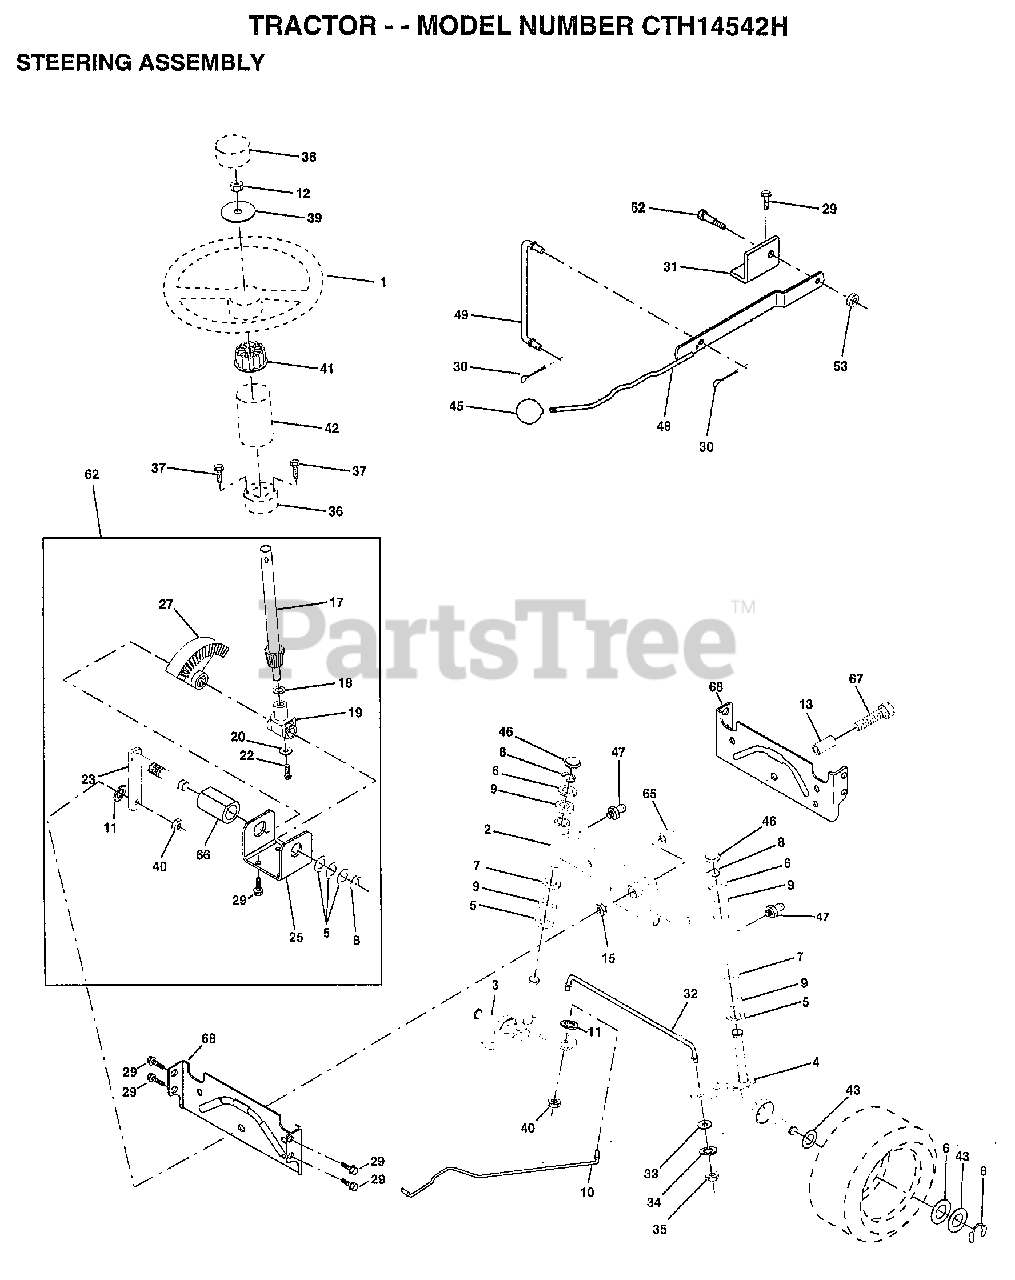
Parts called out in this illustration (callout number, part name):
1	WHEEL STR AYP BLK
2	AXLE ASM
3	SPINDLE.ASM.LH
4	"SPINDLE ASM,RH"
5	WASHER .T
6	WASHER
7	WASHER
8	RING
9	COL. SRTG. BEAR.
10	DRAGLINK-STAMPED
11	LOCKWASHER
13	BEARING AXLE
15	"NUT-LOC,FLANGE LT"
17	SHAFT ASM STEERNG
18	THRUST WASHER
19	SUPPORT.SHAFT
22	SCREW HEX SOC1/4-
25	BRKT-STEERING
27	GEAR SECTOR
29	SCREW
30	COTTER PIN
31	BRKT.PVT.MAN.LVR.
32	ROD.TIE.19.75
33	WASHER M
34	LOCKWASHER
35	NUT.LOCK.5/16-24
36	BUSHING.STRG.3/4
37	"SCREW-TT,10-32 FL"
38	CAP STEER AYP
39	WASHER
40	GRIPCO NUT
41	ADAPTER LT
42	BOOT SHAFT STEER
45	KNOB T (1/2-HOLE)
46	CAP
47	ZERK M
48	LEVER.ASM.CLUTCH
49	LINK CLTCH W/NUTS
52	"BOLT, SHOULDER LT"
62	KIT STEERING ASM
65	SPACER AXLE
66	"BEARING-ARM,PITMA"
67	BOLT
68	BRACE AXLE
